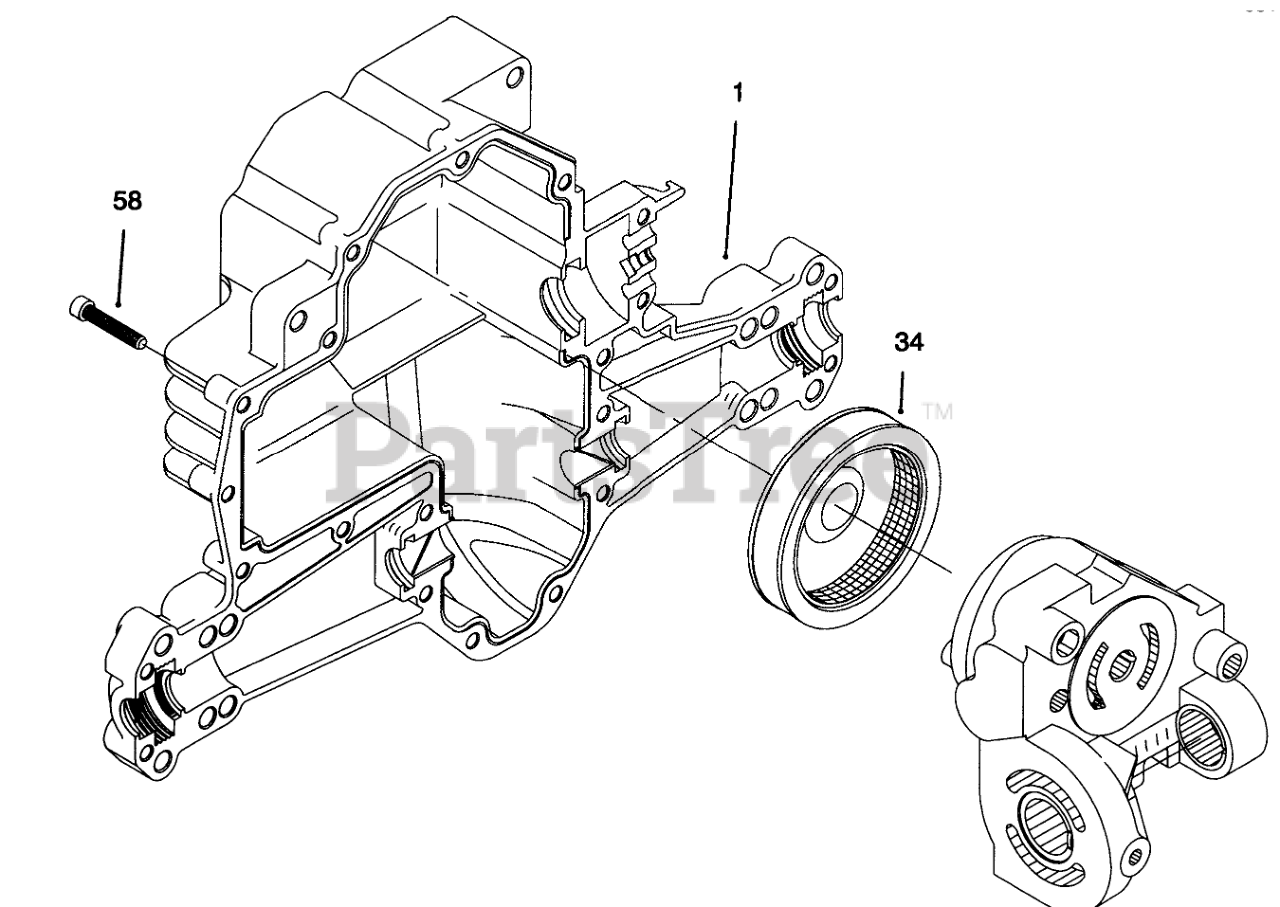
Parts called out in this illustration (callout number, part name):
1	HOUSING - LOWER
15	SEAL-LIP
24	SEAL-LIP
34	ELEMENT - OIL FILTER
